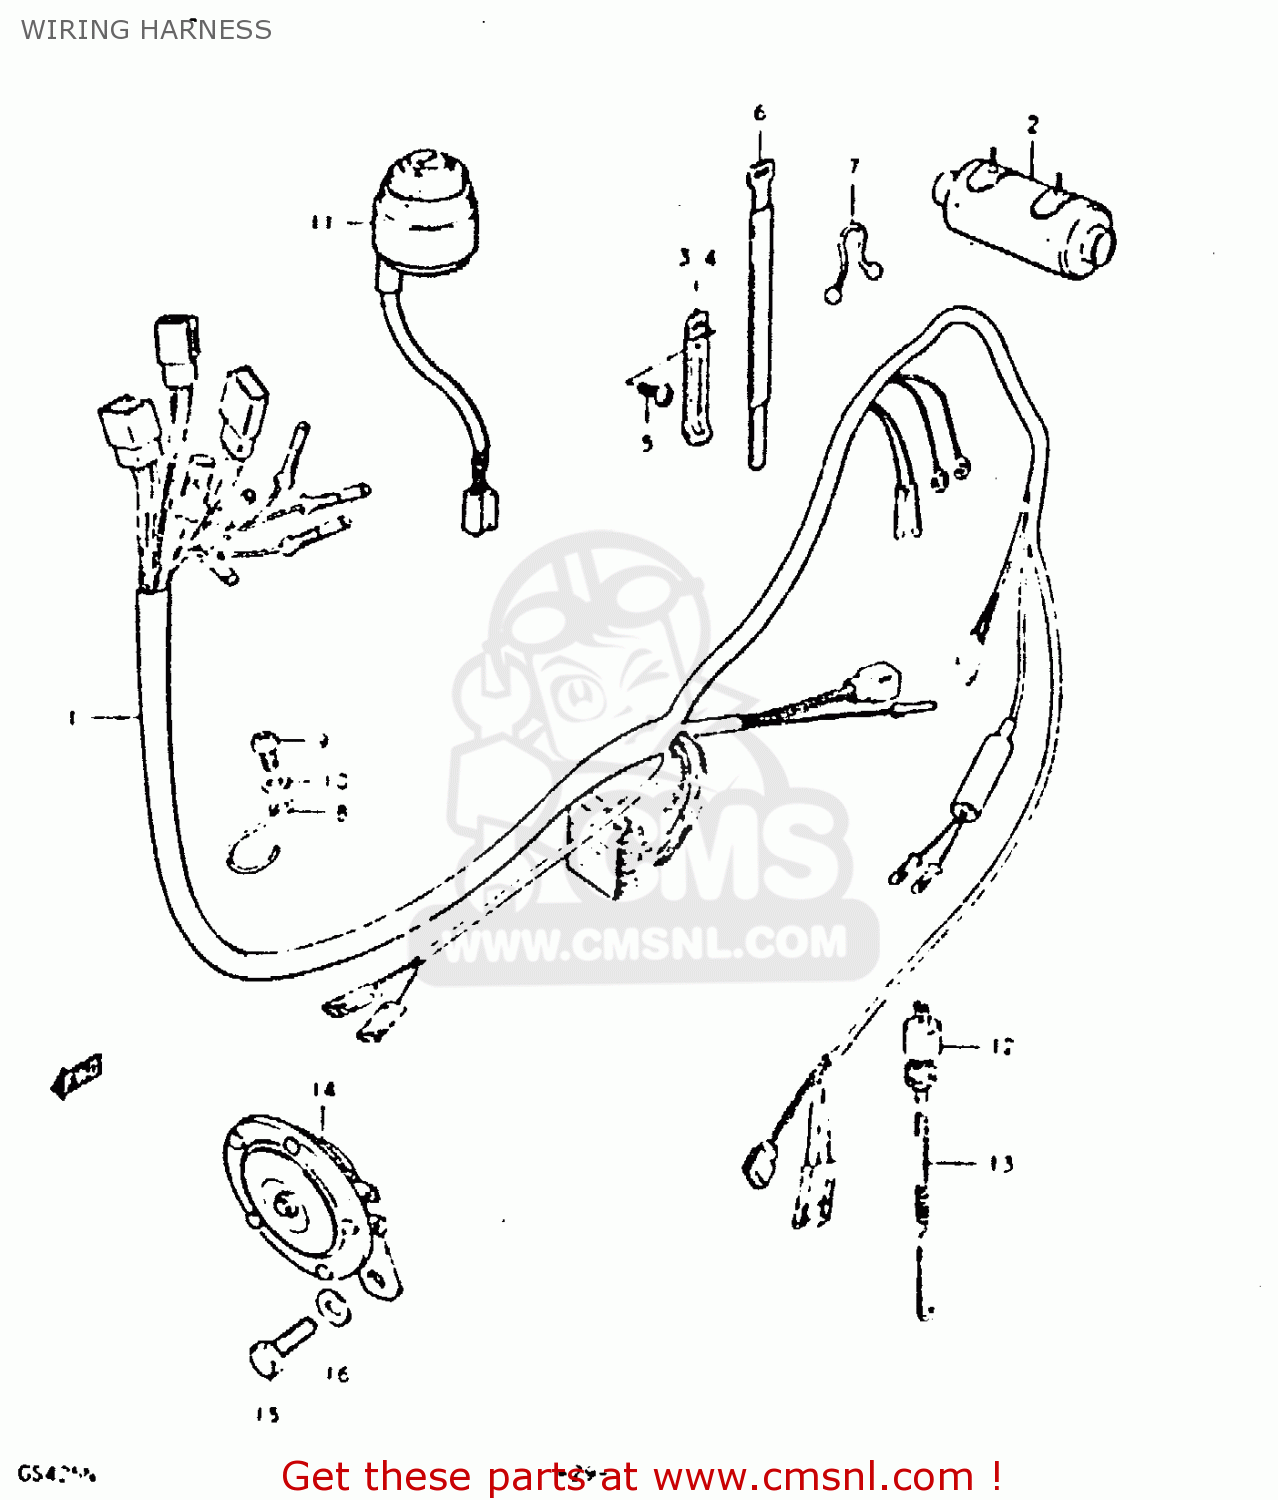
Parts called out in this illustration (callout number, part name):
1	HARNESS,WIRING
2	BOOT,WIRING HARNESS
3	CLAMP
4	CLAMP
5	SCREW
6	CLAMP
7	CLAMP
8	GUIDE,WIRING HARNESS
9	SCREW 6X12
10	WASHER 6MM
11	SWITCH ASSEMBLY,IGNITION
12	SWITCH ASSY,BRAKE LAMP
13	SPRING
14	HORN ASSY
15	BOLT 8X12
16	WASHER
